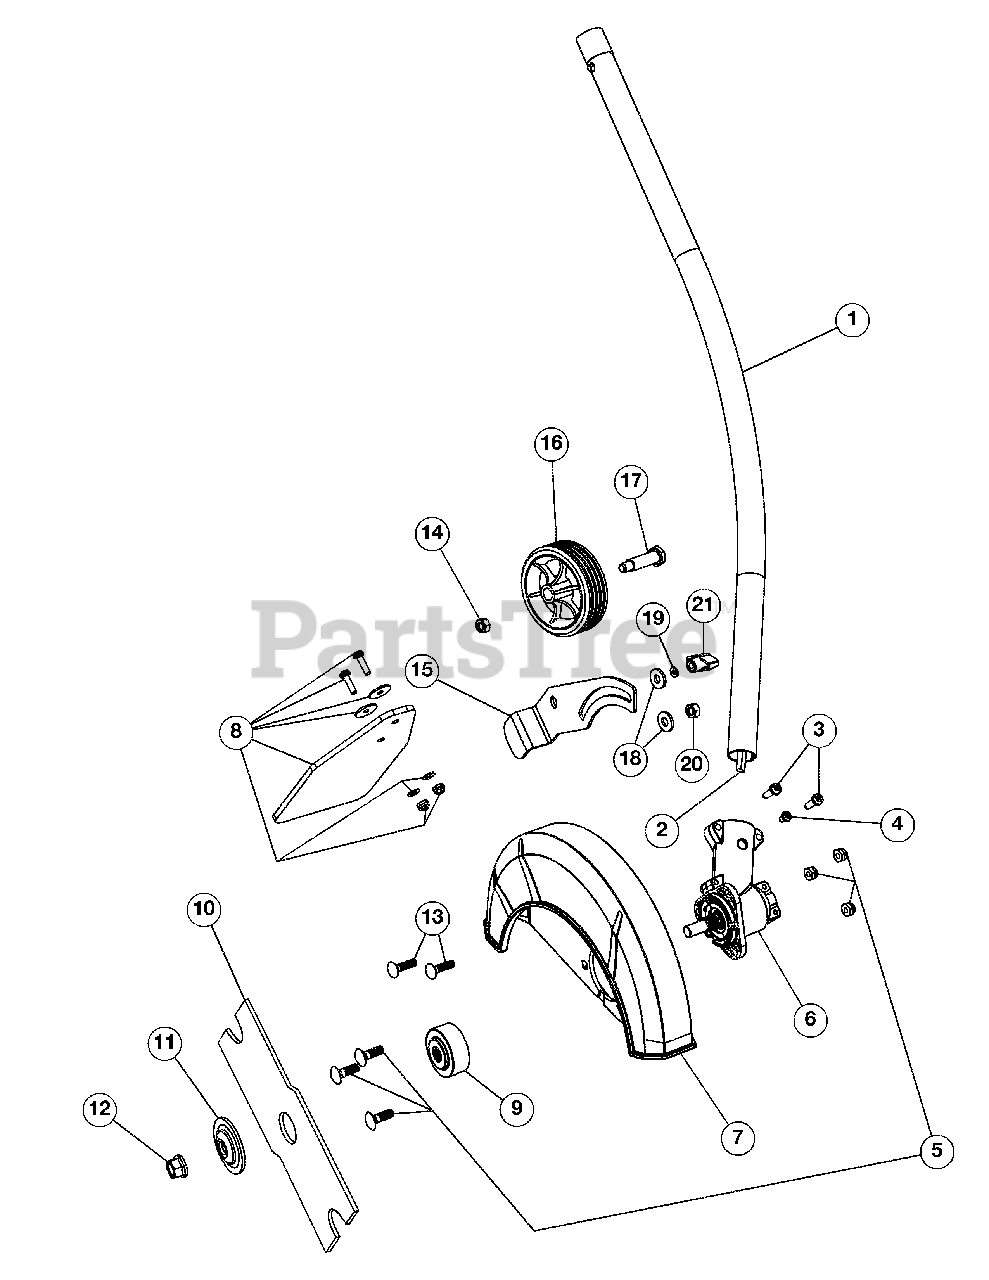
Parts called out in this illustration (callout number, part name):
1	Boom Assembly
2	Drive Shaft
3	Boom Mounting Hardware
4	Anti-Rotation Screw
5	Guard Mounting Hardware
6	Gearbox Assembly
7	Blade Guard
8	Deflector w/Hardware
9	Spacer
10	Blade
11	Blade Clamp Washer
12	Blade Retainer Nut
13	Wheel Bracket Mounting Bolt
14	Nut
15	Edger Guide
17	Shoulder Bolt
19	Washer
21	Edger Guide Knob
